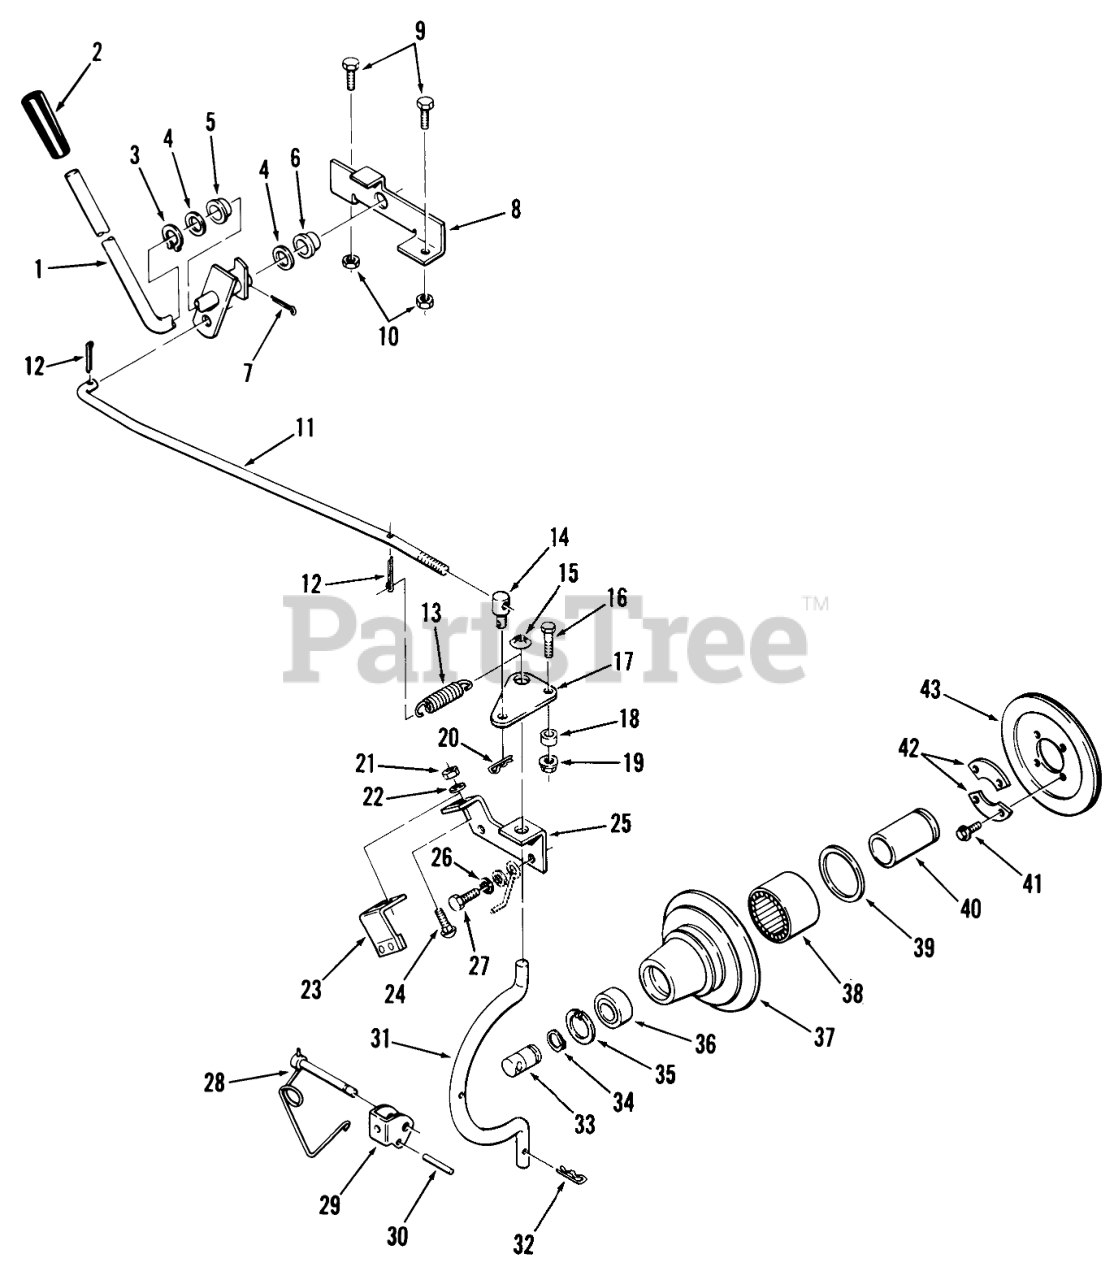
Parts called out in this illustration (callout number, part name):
1	PTO Clutch Lever
2	GRIP
3	Grip Ring
4	SHIM-WASHER
5	BUSHING-NYLINER
6	NYLINER BUSHING
7	Pop Rivet
8	SUPPORT-PTO CLUTCH
9	Bolt
10	Nut
11	PTO Clutch Rod
12	Pop Rivet
13	SPRING
14	TRUNNION
15	RING-REINFORCED CIRC
16	BOLT
17	PLATE R
18	SPACER
19	LOCKNUT-FLANGE
20	Hairpin Cotter
21	Nut
23	PTO Plate
23	PTO Brake Assy
23	ASSY-BRAKE
24	Bolt-Carriage
25	BRACKET
25	Engine Bracket C-111 Only
25	Engine Bracket C-161 Twin Only
25	BRACKET-ENGINE B
26	LOCKWASHER
27	Bolt
27	7/16-14 x 1 1/4 Bolt
28	Pin
29	Clevis
30	PIN-SPIROL
31	ROD-HOUSING
32	Hairpin
33	SHAFT-PTO
34	RING-SNAP, EXTERNAL
35	Ring-Snap
36	BaIl Bearing
37	Housing-Clutch
38	BRG-NEEDLE OPEN END
39	SEAL-OIL
40	RACE-BEARING
40	BEARING RACE
41	Screw
42	RETAINER
43	Clutch Plate & Facing
